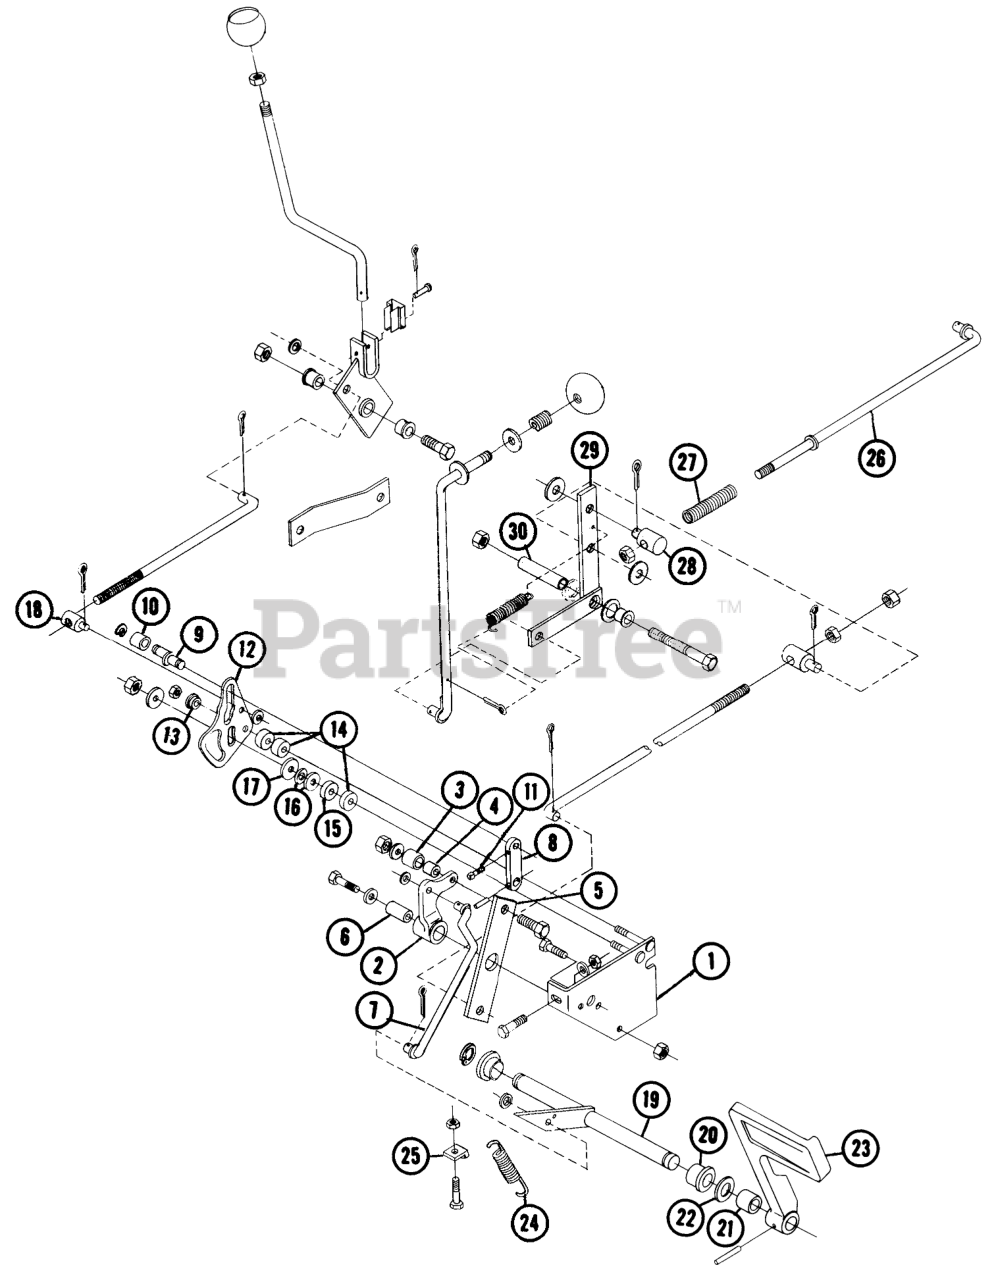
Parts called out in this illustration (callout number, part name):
1	WASHER 5/16 SAE
3	BEARING-CAM RETURN
9	ECCENTRIC-CAM FOLLOW
10	BEARING CAM ROLLER
10	E RING
13	CAM-SPACER
16	WASHER-SPRING DISC
17	FRICTION WASHER
20	BEARING
20	E-RING
22	WASHER
23	PIN-ROLL, SPIROL
25	CLIP - SPRING
28	TRUNNION-LIFT
30	Spacer
